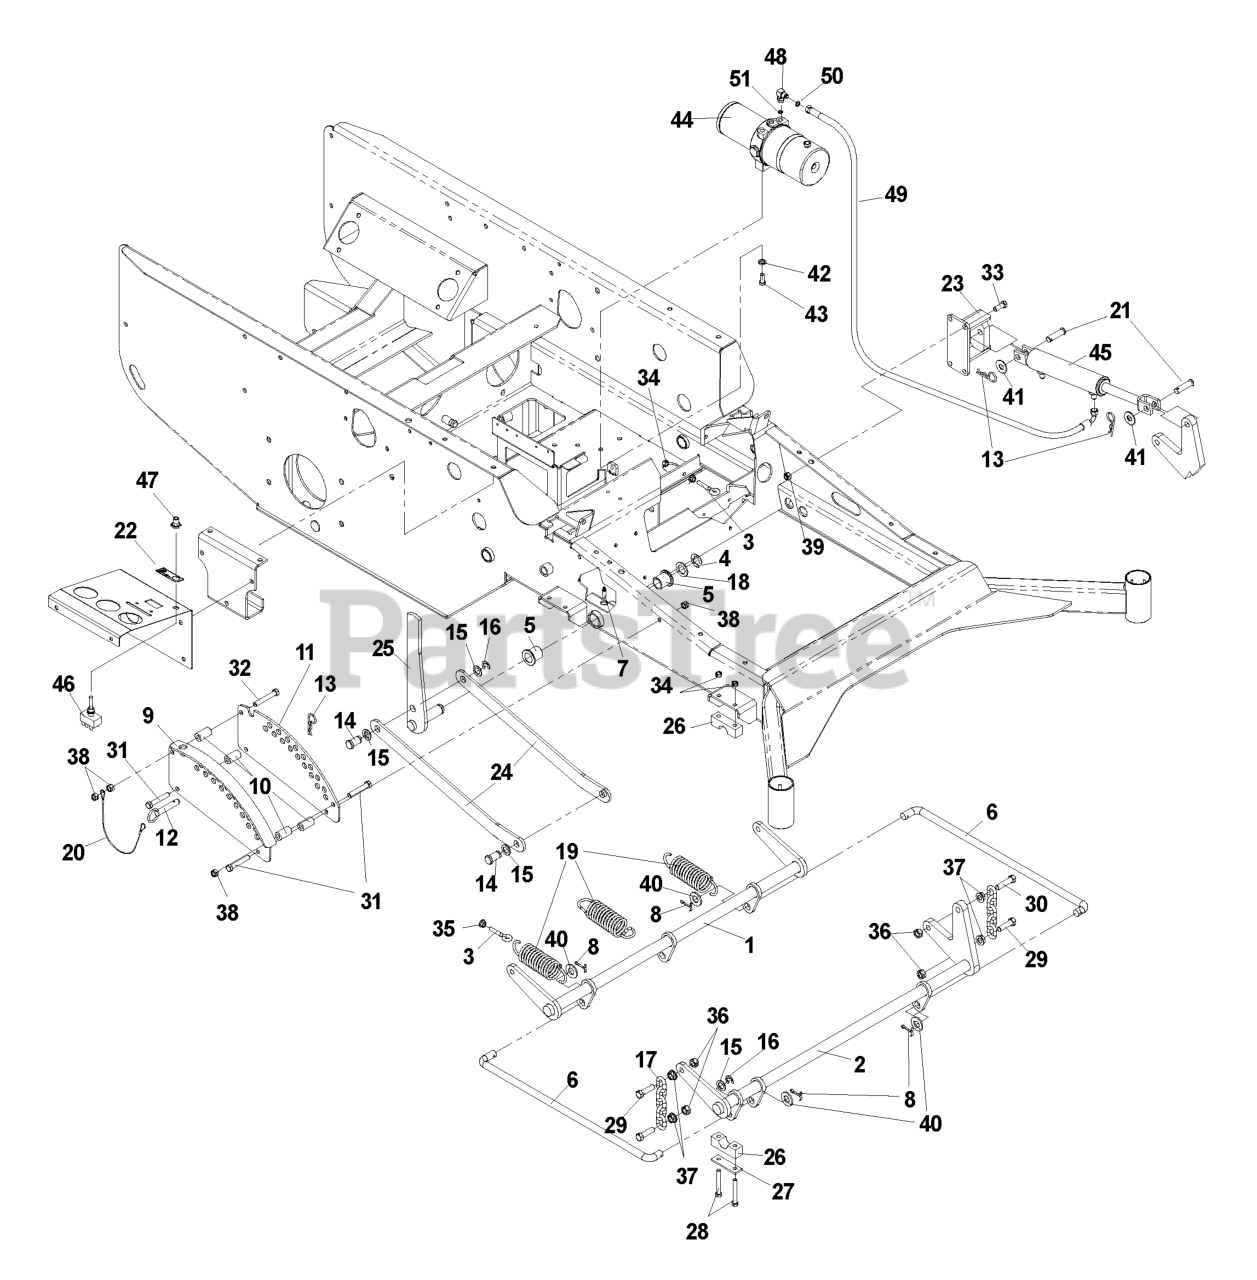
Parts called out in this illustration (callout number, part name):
1	SHAFT LIFT REAR
2	LIFT SHAFT WELDMT FRONT
3	EYEBOLT, RH
4	E-RING 7/8
5	BUSHING, FLANGED
6	CONNECTING LINK
7	GREASE ZERK LONG
8	COTTER PIN
9	ADJ. PLATE WLDMNT
10	DECK LIFT SPACER
11	ADJ. PLATE PAINTED
13	HAIRPIN #4
14	CLEVIS PIN
16	E-RING 5/8
17	LIFT CHAIN
18	BSHG .875 X 1.375 X .074 ZD
19	DECK LIFT SPRING
21	CLEVIS PIN 1/2 X 3/4
22	DECAL, LIFT SWITCH
23	CYLINDER MTG WLDMT
24	LIFT LINKAGE,PAINTED
25	LIFT LEVER
26	PILLOW BLOCK
27	REINFORCEMENT BAR
28	BOLT 5/16C X 2 1/2
29	HCS 7/16C X 1 1/2
30	HCS 7/16 - 14 X 1 3/4
31	HCS 3/8C X 2 1/4
32	HCS 3/8C X 2 1/2
33	HCS 3/8-16X1.GRD.5.ZD
34	NUT 5/16C CENTERLOCK
35	NUT 5/16C WHIZ
36	NUT 7/16C CENTERLOCK
37	NUT 7/16C WHIZ
38	NUT 3/8C CENTERBLOCK
39	NUT 3/8-16 NYLOC
40	WASHER 5/8 FLAT
41	WASHER 1/2 FLAT
42	SLW 3/8 STD
43	SCREW 3/8C X 3/4 HEX CAP
44	HYDRAULIC POWER UNIT
45	HYDRAULIC CYLINDER
47	SWITCH BOOT
